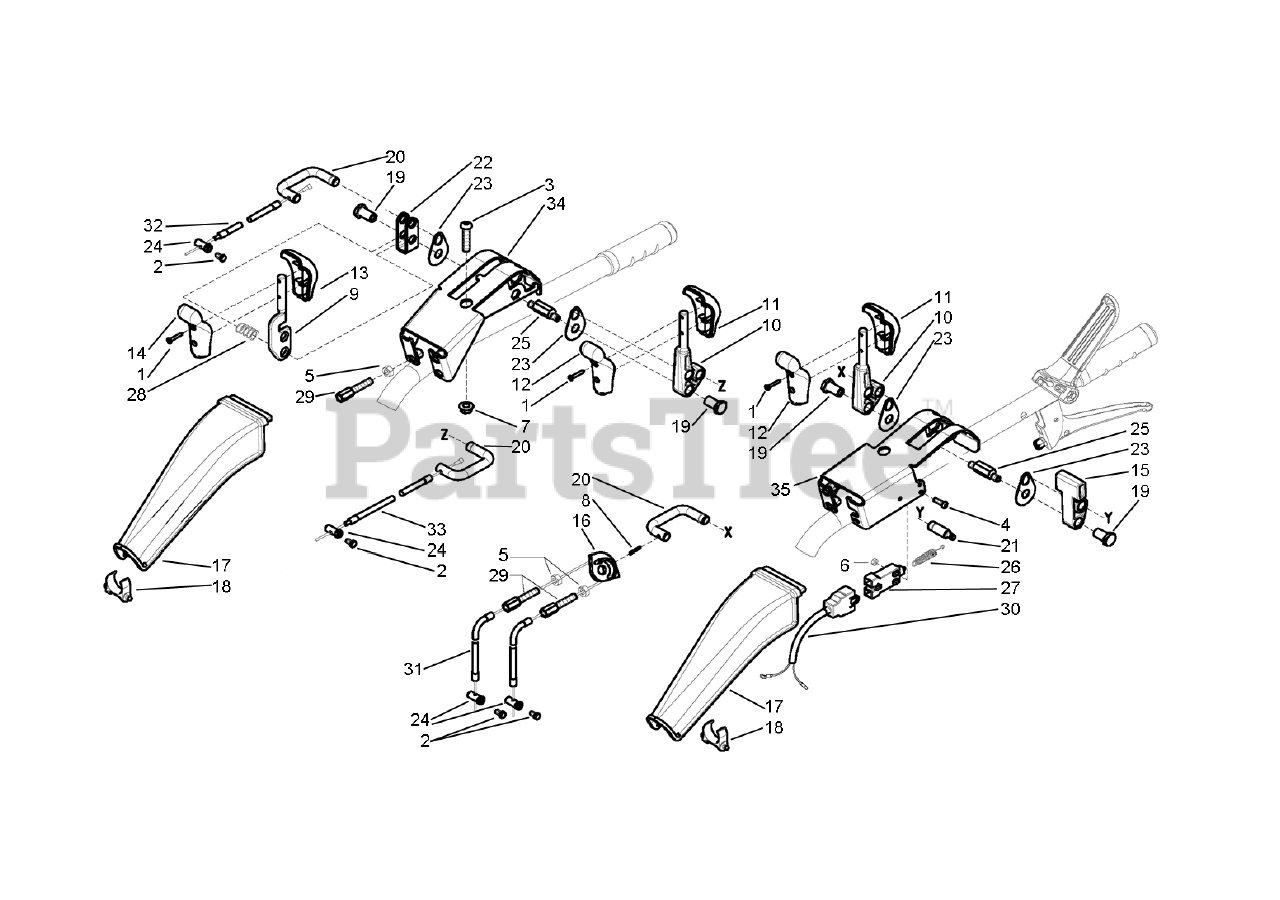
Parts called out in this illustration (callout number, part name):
1	SCREW 3,5X25
2	SCREW TE M6X16
3	SCREW
4	SCREW, 4X25
5	NUT M8 UNI 5588 6S
6	SELFLOCK NUT M4 FL.6S DIN6927
7	SELFLOCK NUT M8 6S DIN 6927
8	ROLL PIN 4X20 SPIROL
9	LEVER, FORWARD/REVERS
10	LEVER
11	UPPER HANDLE HALF, BLACK
12	LOWER HANDLE HALF, BLACK
13	UPPER HANDLE HALF, RED
14	LOWER HANDLE HALF, RED
15	LEVER, ON/OFF
16	PULLEY
17	COVER
18	CROSSPIECE
19	STUD BOLT
20	U BOLT
21	INDEXING BOLT
23	SMALL PLATE
24	CLAMPING SCREW
26	SPRING
27	SWITCH
28	SPRING
29	ADJUSTING SCREW
30	WIRING
31	CABLE & SHEATH, PARKING BRAKE
32	CABLE & SHEATH, REVERSE
33	CABLE & SHEATH, DIFFERENTIAL
34	SUPPORT, CONTROLS RH
35	SUPPORT, CONTROLS LH
